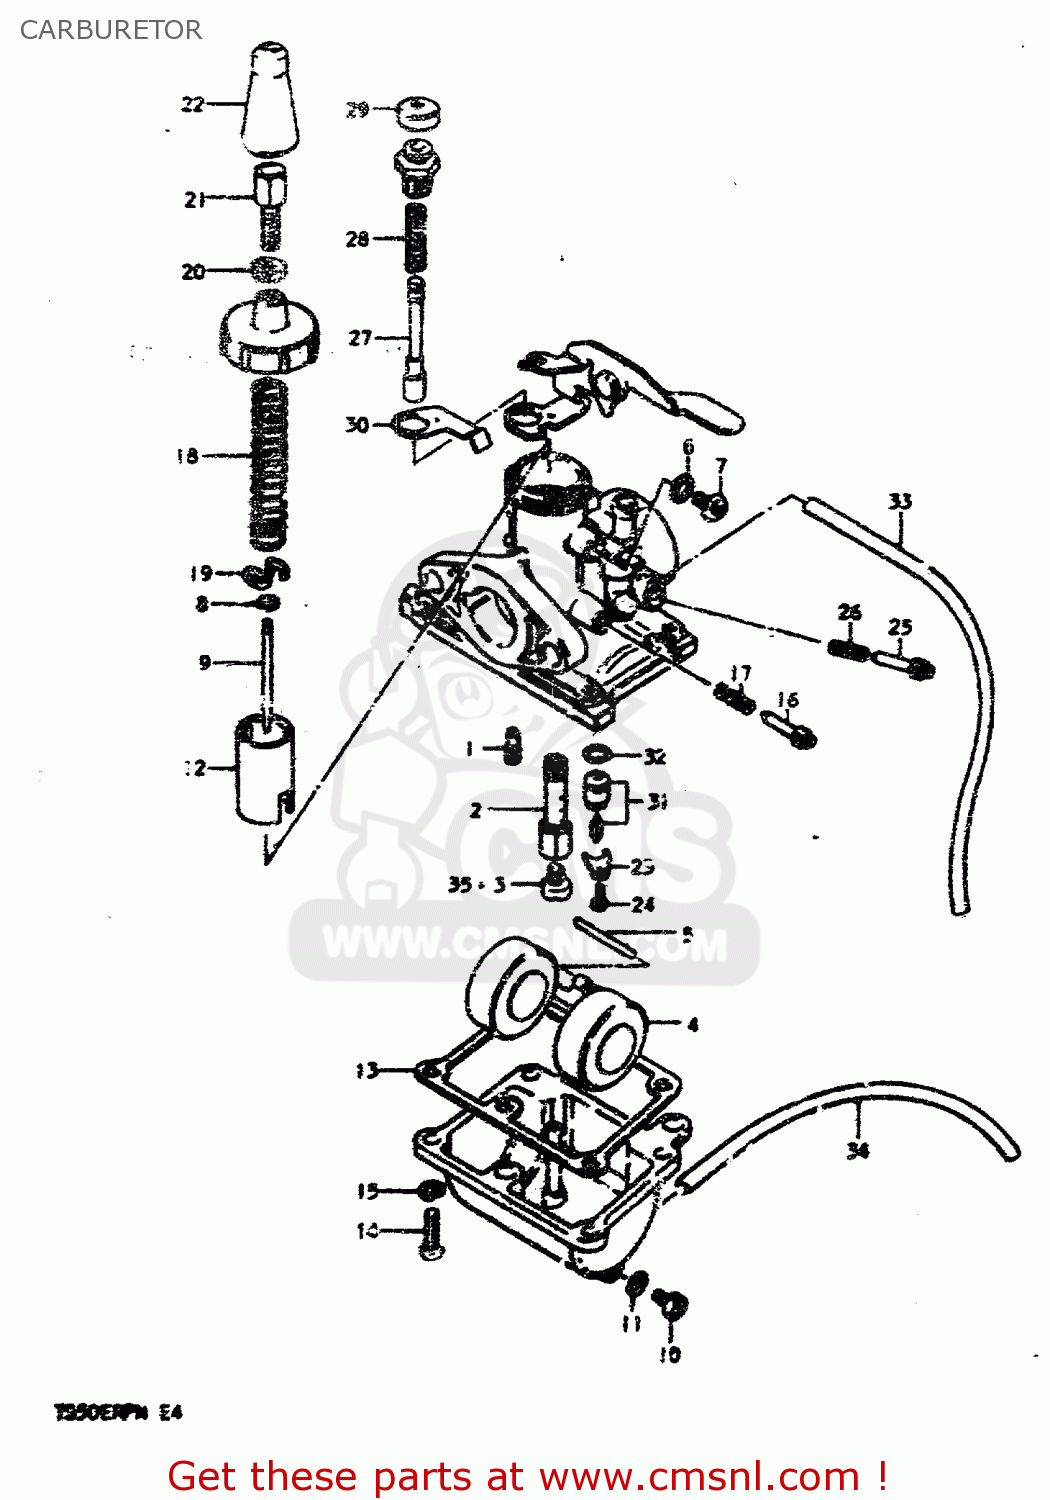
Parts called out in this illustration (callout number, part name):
1	JET,PILOT
2	JET, NEEDLE (E-7)
3	JET,MAIN(70)
4	FLOAT
5	PIN,FLOAT
6	RING
7	SCREW
8	CLIP,NEEDLE
9	NEEDLE,JET
10	PLUG
11	GASKET,DRAIN,PLUG (NAS)
12	VALVE,THROTTLE(CA:2.0)
13	GASKET,FLOAT CHAMBER (NAS)
14	SCREW
15	LOCK WASHER
16	SCREW,THROTTLE STOP
17	SPRING
18	SPRING,THROTTLE VALVE RETURN
19	PLATE,THROTTLE VALVE
20	NUT
21	ADJUSTER,CABLE
22	CAP
23	PLATE,NEEDLE VALVE FITING
24	SCREW
25	SCREW,AIR
26	SPRING
27	VALVE,STARTER
28	SPRING
29	CAP
30	SPRING
31	VALVE ASSY,NEEDLE
32	O-RING,NEEDLE VALVE
33	HOSE
34	HOSE
